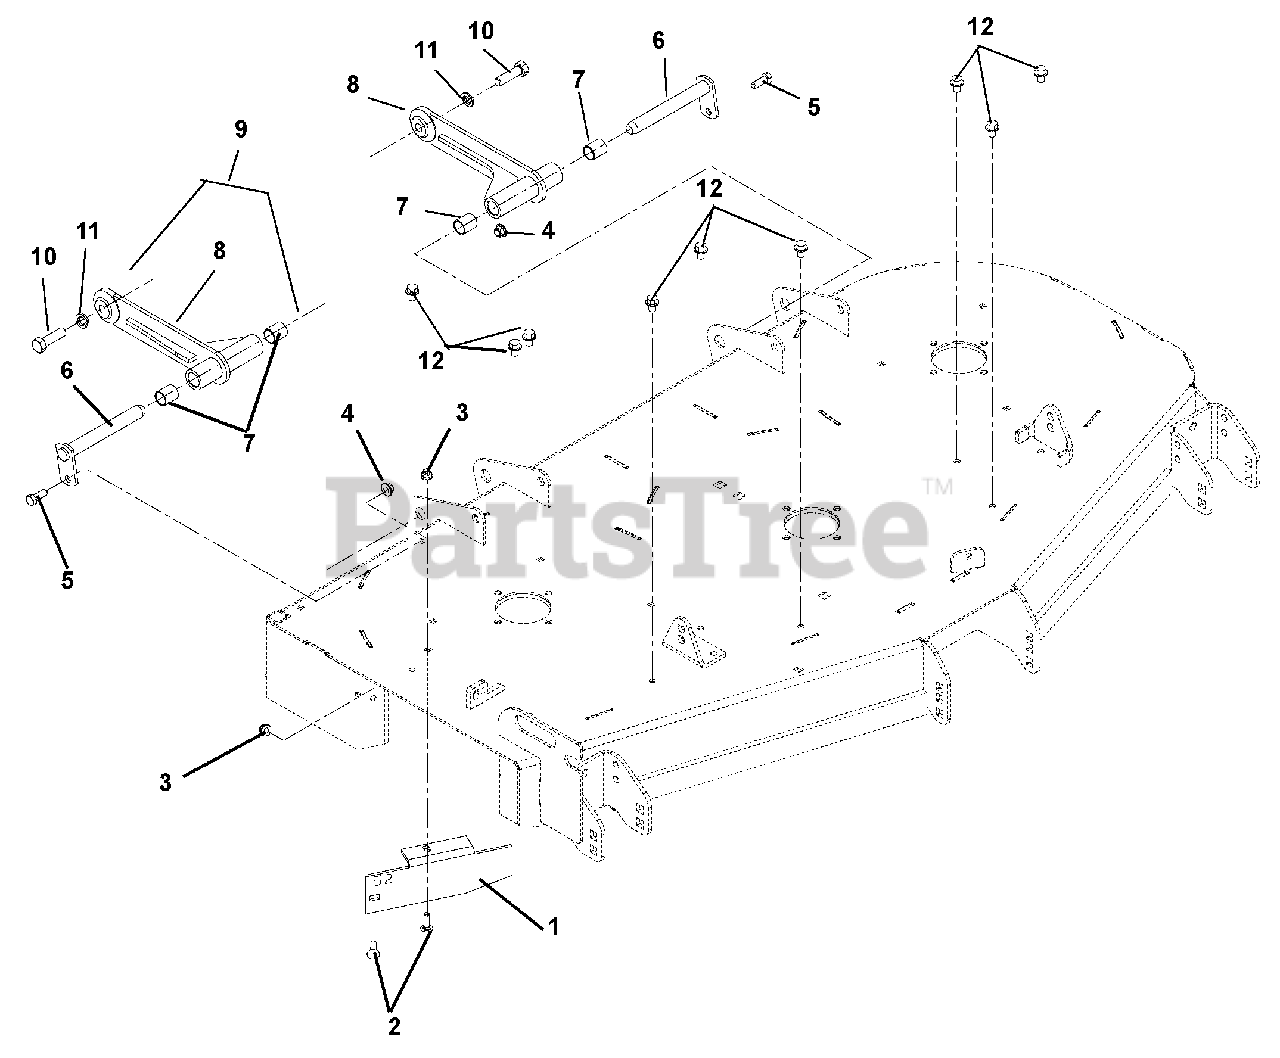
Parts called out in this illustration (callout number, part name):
1	52" Discharge Baffle (069)
2	Bolt, Round Head Square Neck .31-18 x 1.00 Grade 5
3	Nut, .31-18 Nyloc Flange
4	Nut, .38-16 Nyloc Flange
5	Bolt-Hex .38-16X1.00 Grade 5
6	Weldment, Mower Mounting Pin
7	Bearing, .75 x .875 x 1.00
8	Deck Pusher Arm Weldment
9	Assembly, Mower Mount Arm (Contains items 7 and 8)
10	Bolt, Hex .50-13 x 1.75 Grade 5
11	Washer, Locking .50 x .125 Regular
12	Screw, Tapping .38-16 x .50 Hex Washer Head
